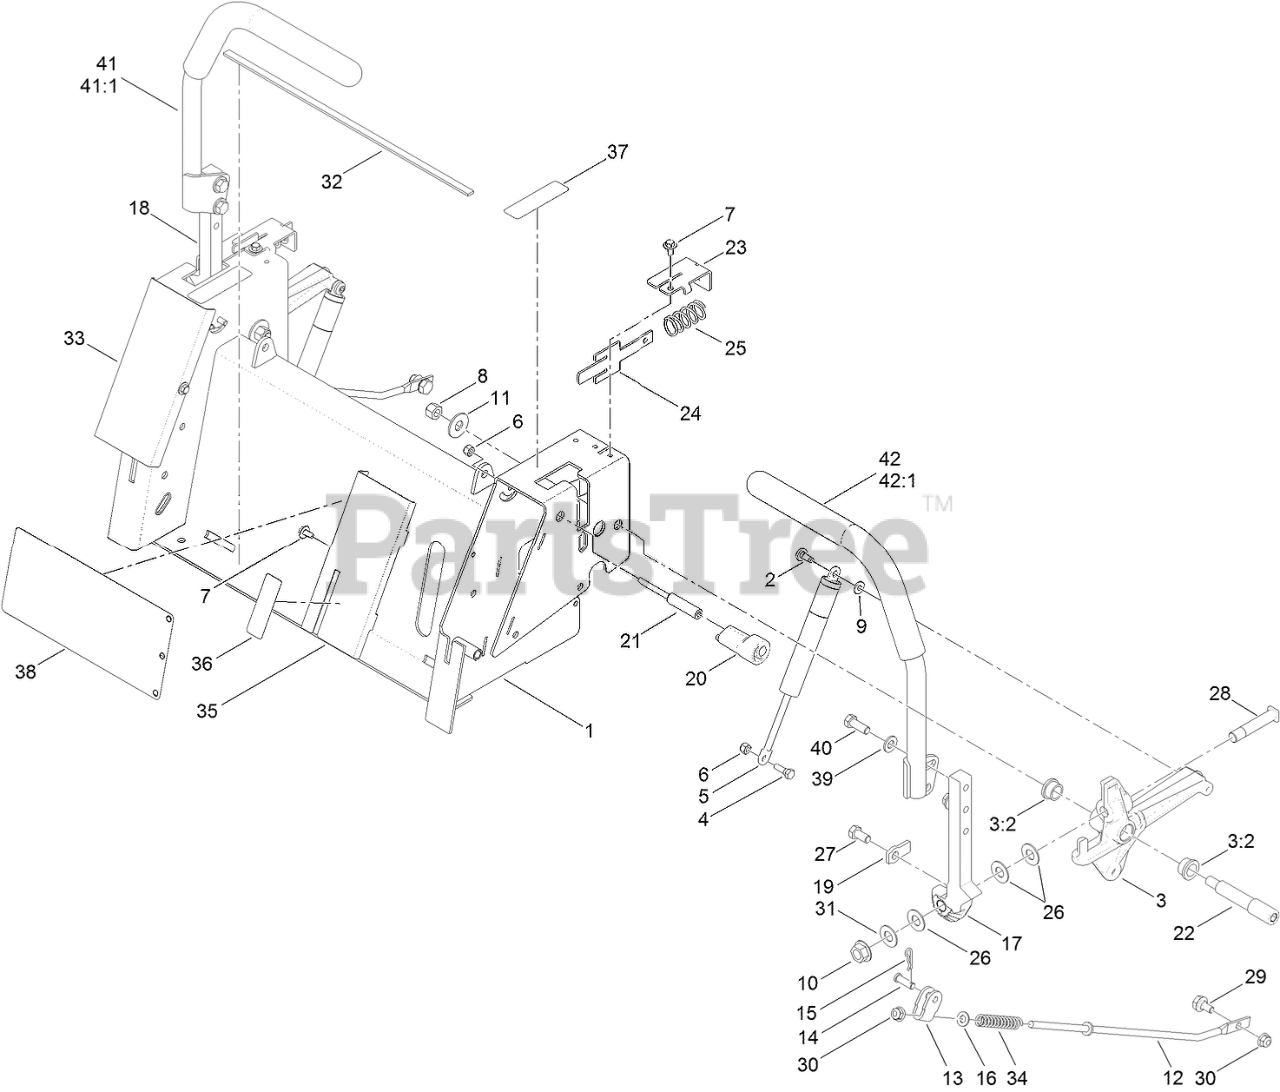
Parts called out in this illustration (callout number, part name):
1	BOX-CONTROL
2	SCREW-SHOULDER
3	ACTIVATOR ARM ASM
3:2	BUSHING
4	BOLT-SHOULDER
5	DAMPER-CONTROL, MOTION
6	NUT-LOCK, NI
7	SCREW-HHFTF
8	NUT-LOCK, NI
9	WASHER
10	NUT-HF
11	WASHER-FLAT
12	ROD-CONTROL
13	BRACKET-CONTROL
14	PIN-CLEVIS
15	PIN-COTTER
16	WASHER-PLAIN
17	ARM-ACTUATOR, LH
18	ARM-ACTUATOR, RH
19	TAB-STOP
20	ECCENTRIC
21	SCREW-ECCENTRIC
22	BOLT-SHOULDER
23	BRACKET-RETURN
24	PLATE-RETURN
25	SPRING-COMPRESSION
26	WASHER-PIVOT
27	SCREW-HH
28	BOLT-SHOULDER
29	BOLT-SHOULDER
30	NUT-HF, NI
31	WASHER-TEFLON
32	STRIP-VIBRATION, ANTI
33	COVER-CONTROL, RH
34	SPRING-RETURN, NEUTRAL
35	COVER-CONTROL, LH
36	DECAL-BRAKE, PARKING
37	DECAL-CONTROL, MOTION
39	WASHER-FLAT
40	SCREW-HH
41	HANDLE-CONTROL, RH
42	HANDLE-CONTROL, LH
